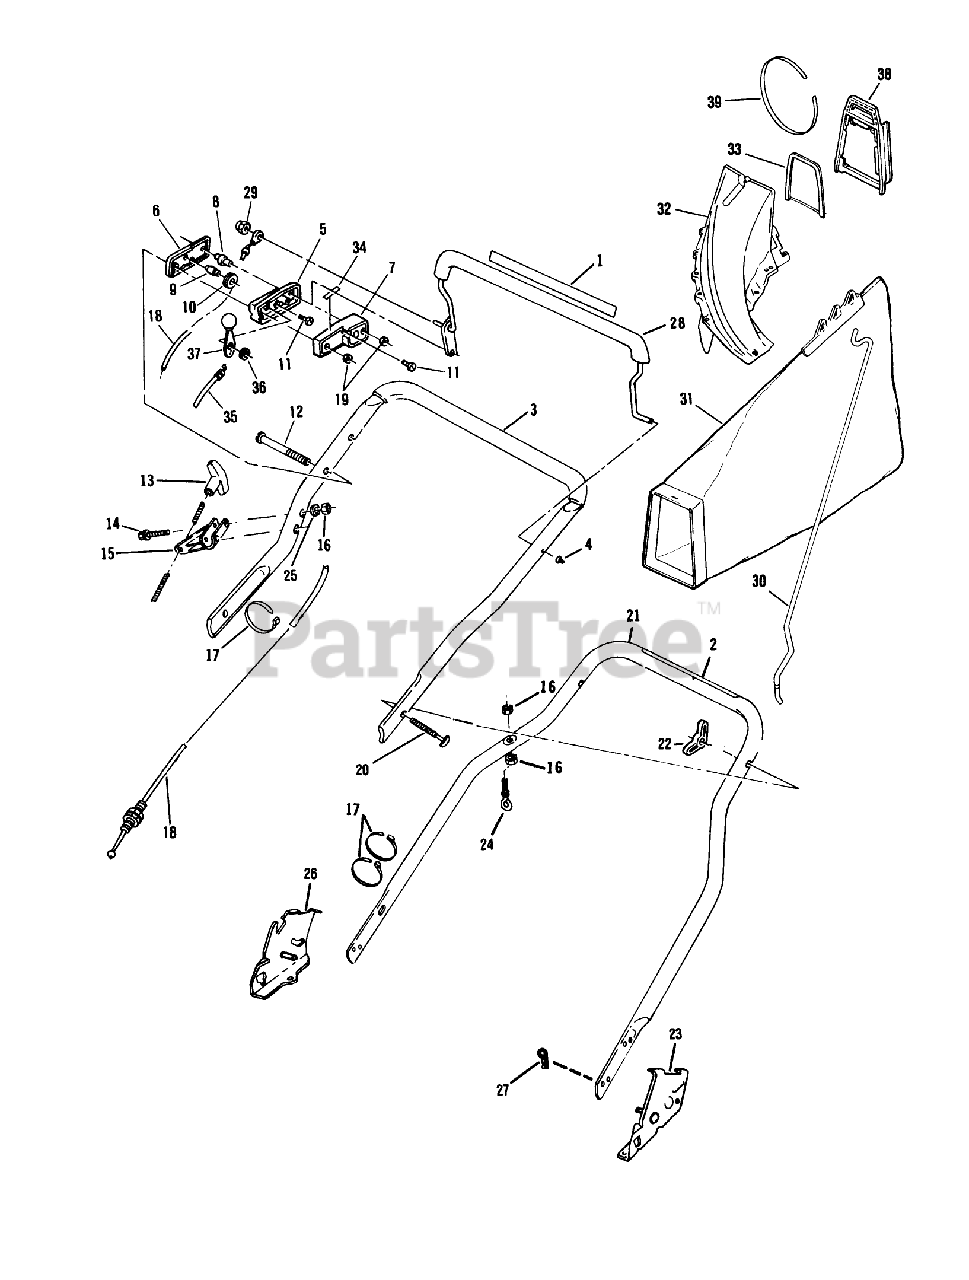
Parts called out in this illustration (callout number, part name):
8	COLUMN
9	PIN SKF
10	PULLEY PL
11	SCREW
12	SCREW
13	HANDLE START UM&D
16	LOCKNUT E
18	CONTROL CABLE WES
19	NUT C/LOCK E
20	BOLT QUALITY
22	NUT-WING
24	EYE BOLT WAS MFG
25	WASHER
27	HAIR PIN
29	NUT ACORN
30	ROD GRASSBAG
31	ORDER 89816 THRU WHOLE GD
33	CHUTE BRACE
35	CABLE TH'TTLE WES
36	WASHER-SPRING
37	LEVER&KNOB AY WES
38	CHUTE - ADAPTER
